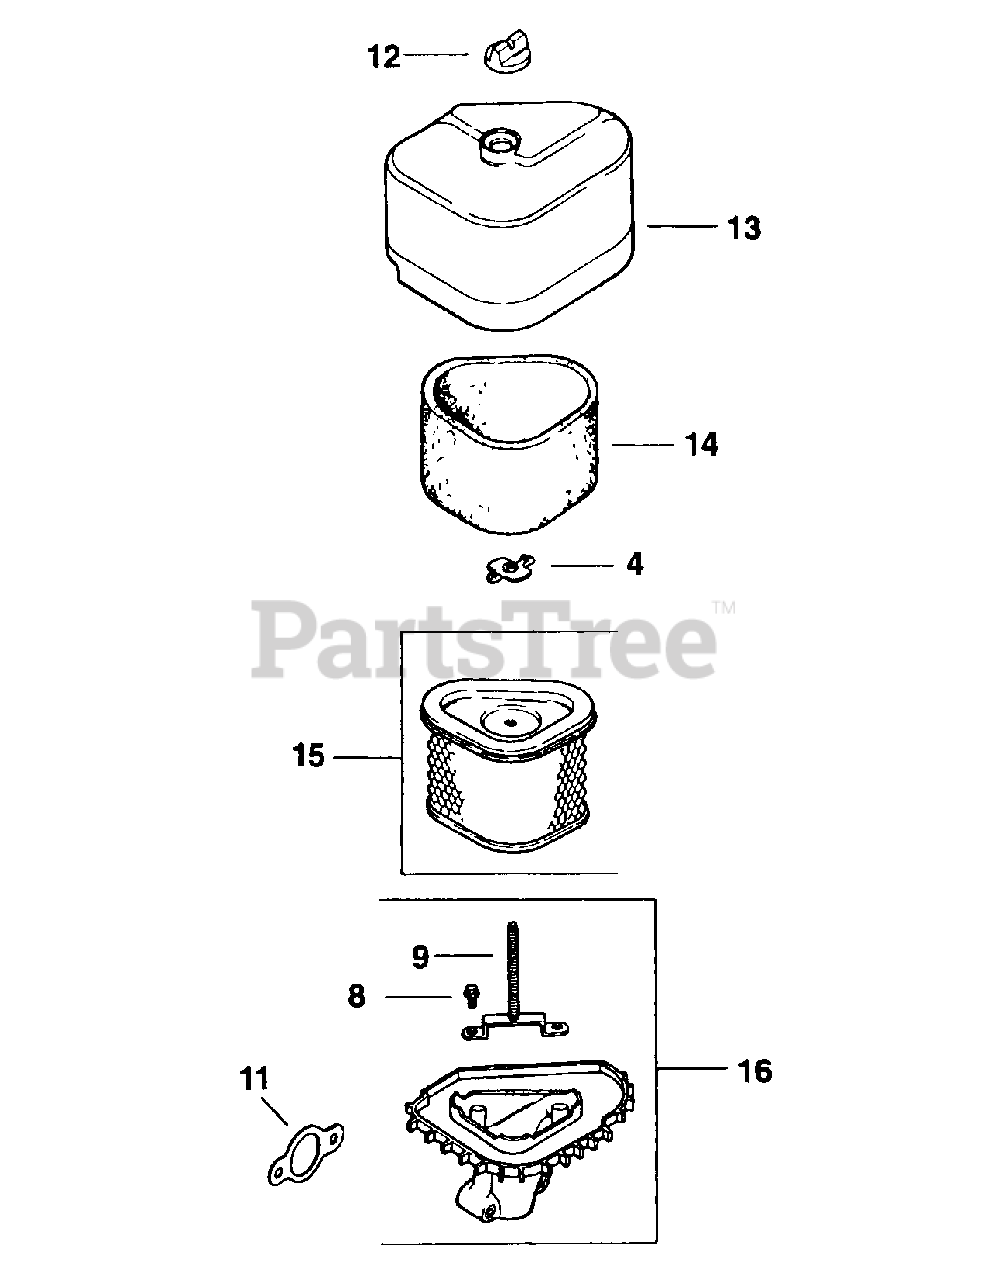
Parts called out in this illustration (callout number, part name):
4	Nut, Wing
8	Screw, Hex Cap #10 Hi-Lo
9	Stud, Mounting Plate
11	Gasket, Air Cleaner
12	Knob, Air Cleaner Cover
13	Cover, Air Cleaner
14	Precleaner
15	Elements, Air Cleaner & Precleaner
16	Base, Air Cleaner
